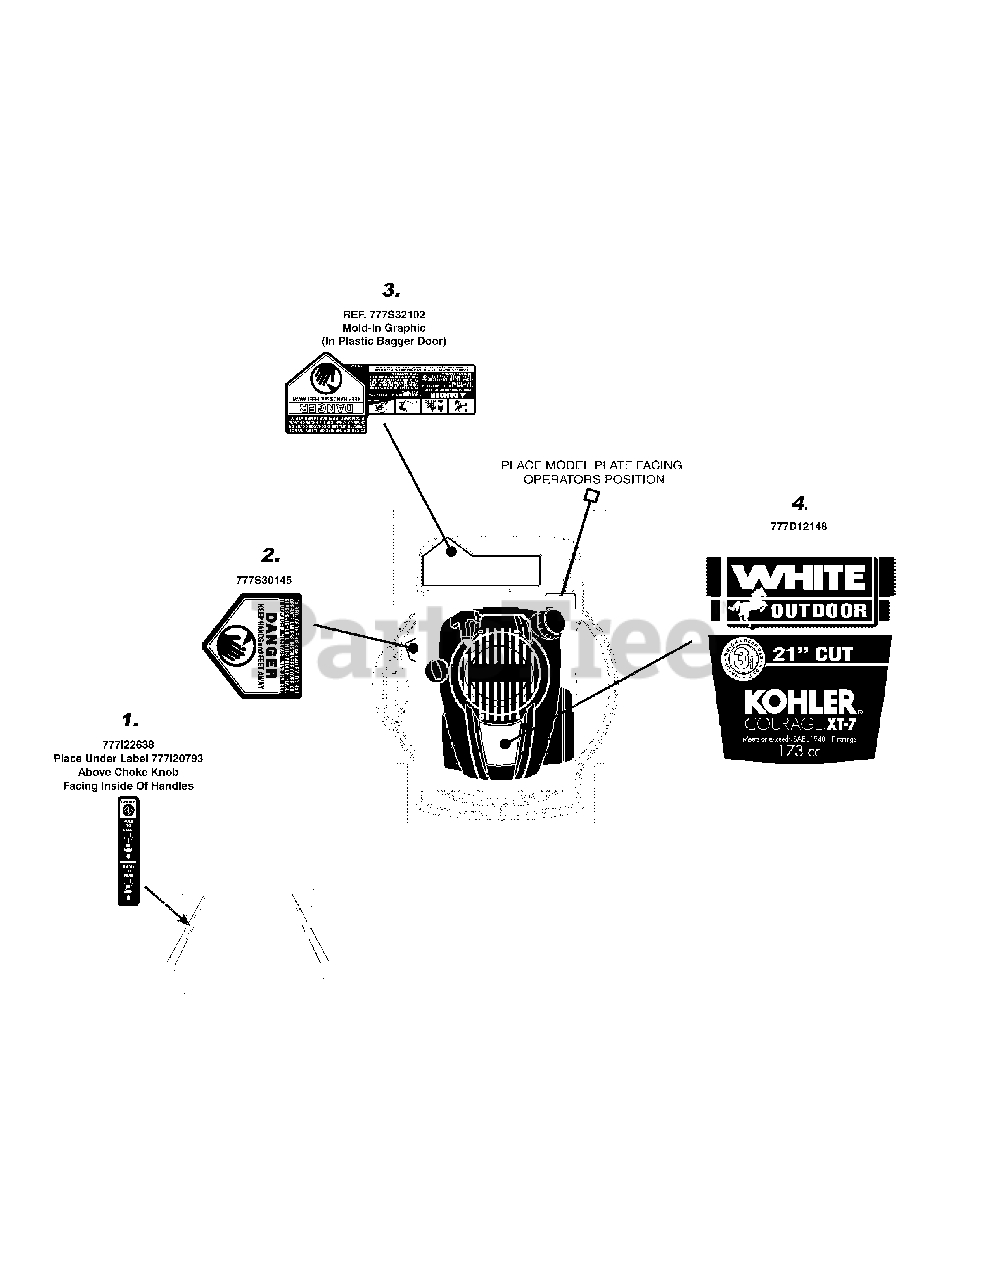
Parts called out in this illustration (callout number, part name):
1	LBL:MWR:HNDL:CHOKE STRT/RUN
2	LABEL
3	LBL:DANGER
